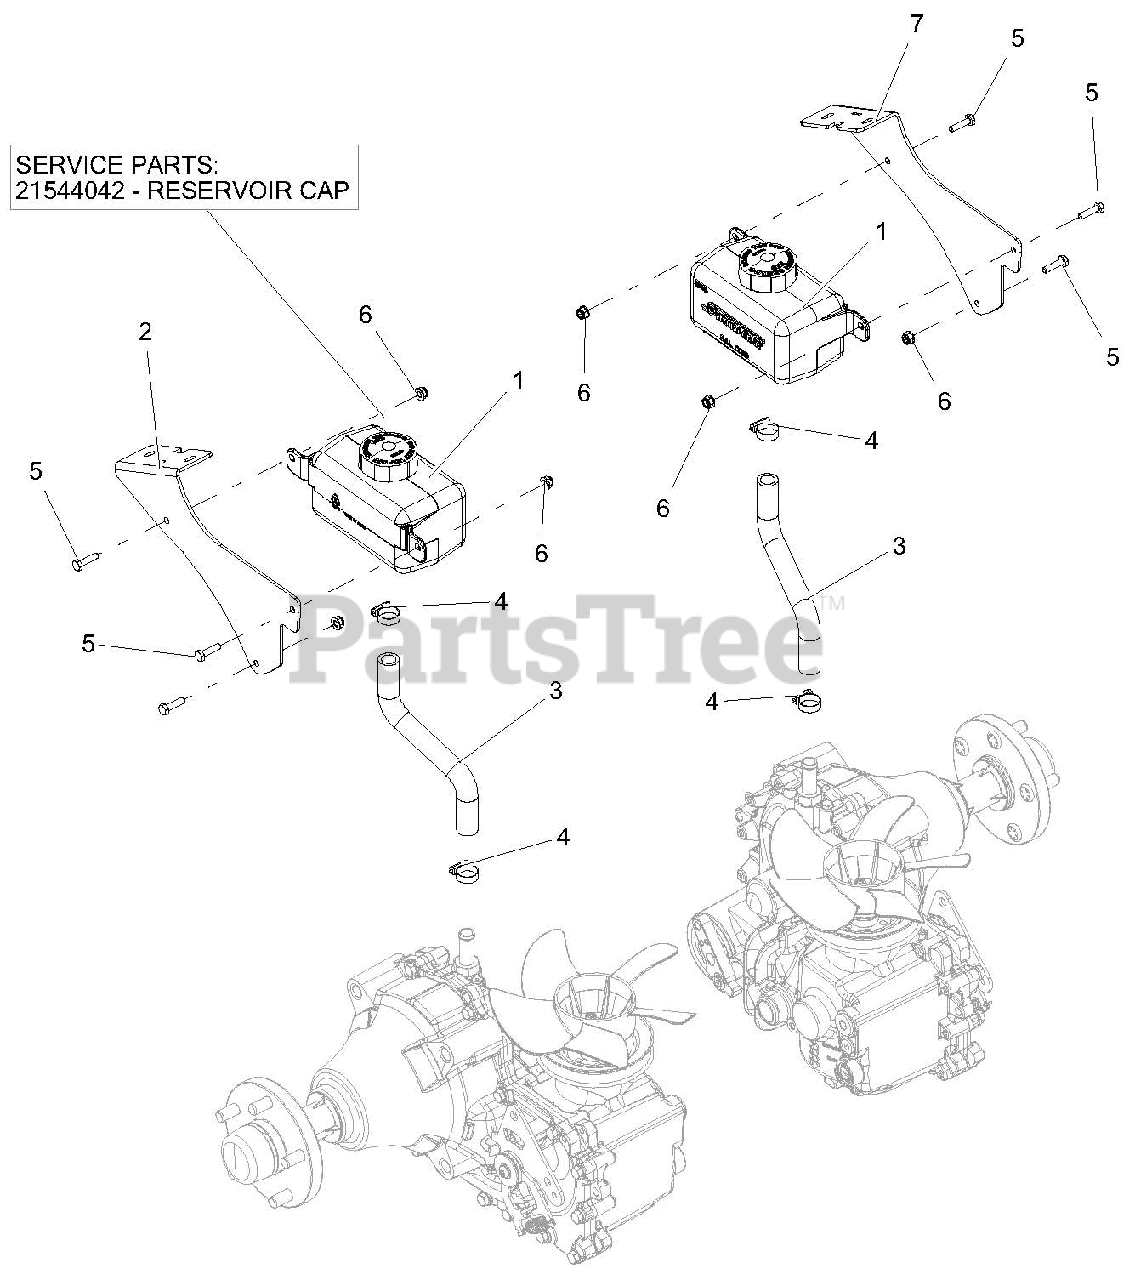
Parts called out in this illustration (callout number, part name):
1	TANK, HYD 1000ML
1	RSERVOIR CAP
2	BRKT, MOUNT RH HYDRO OVERFLOW TANK CARB CANISTER MTG
3	HOSE, HYDRO OVERFLOW
4	CLAMP, .88 DIA HOSE
5	BLT-HEX .25-20X1.00 GR5 YWZC
6	NUT-LK-NYL-FLG .25-20 YWZC
7	LH HYDRO OVERFLOW TANK CARB CANISTER MTG
